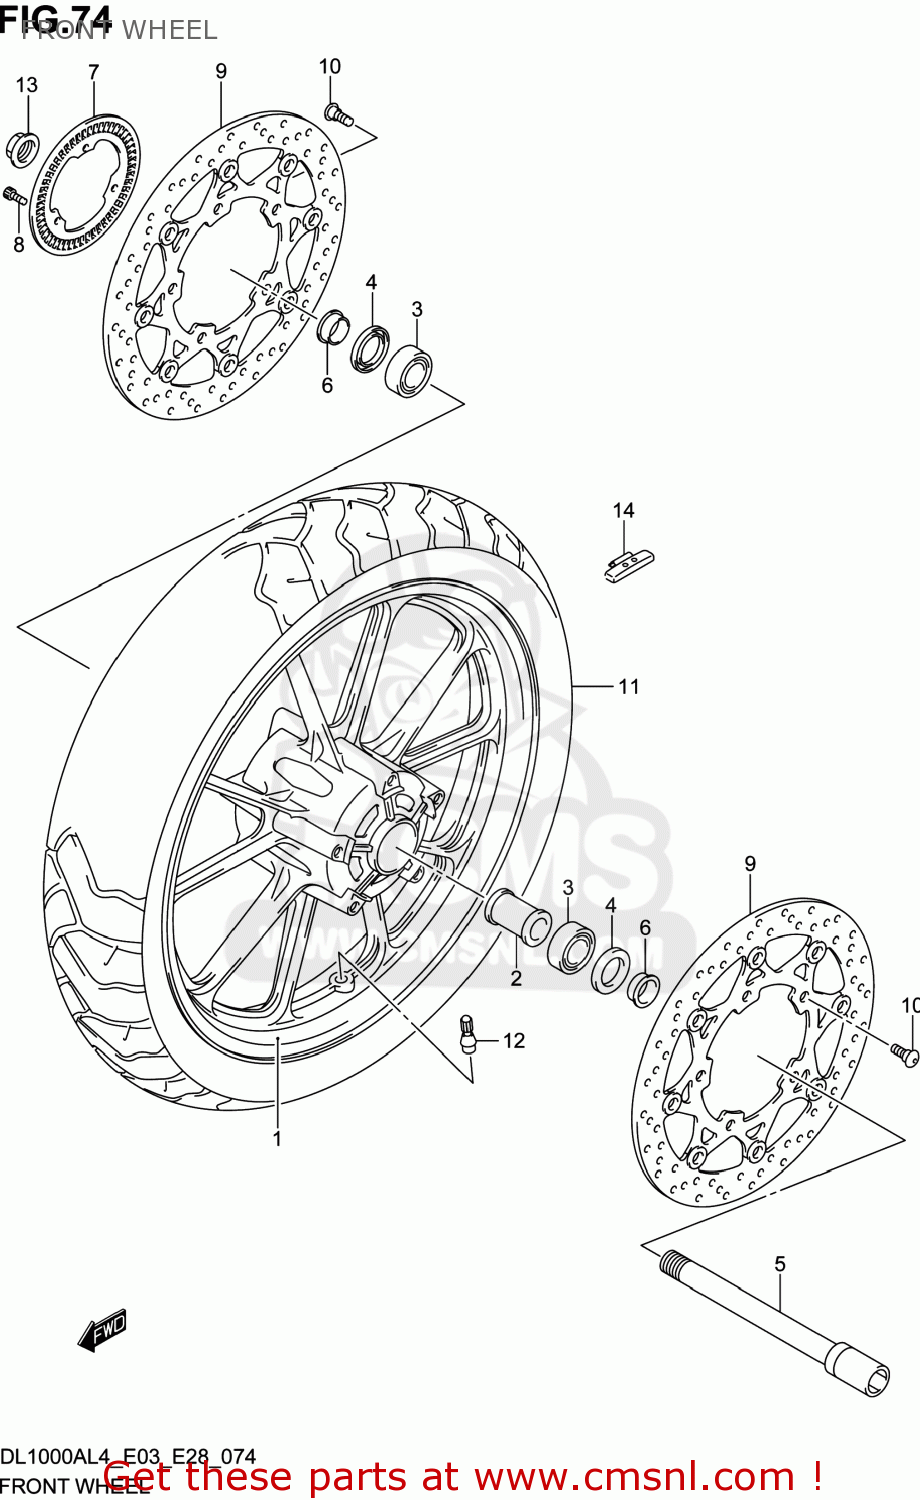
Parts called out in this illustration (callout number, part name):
1	WHEEL,FRONT(19M/CXMT2.50)
2	SPACER,FR HUB BEARING
3	BEARING(25X52X15)
4	SEAL,OIL(32X52X7)
5	AXLE,FRONT
6	SPACER,FR AXLE,R
7	RING,SPEED SENSOR FR(50T)
8	BOLT
9	DISC,FRONT BRAKE
10	BOLT(8X21)
11	TIRE,FRONT
12	VALVE ASSY,WHEEL RIM(TR412)
13	NUT,FR AXLE
14	BALANCER,WHEEL(10G)
